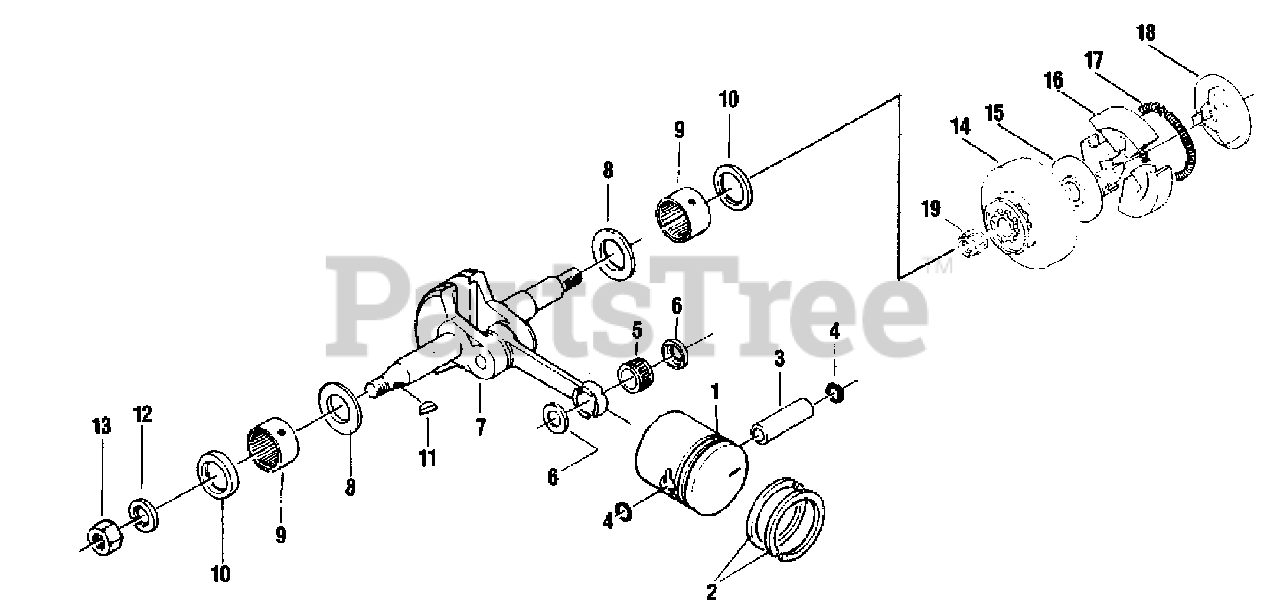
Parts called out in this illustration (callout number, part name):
1	PISTON
2	RING, PISTON
3	PIN, PISTON
4	RING, RETAINING
5	BEARING, NEEDLE
6	WASHER, THRUST
7	CRANKSHAFT ASSY
8	WASHER, THRUST
9	BEARING, NEEDLE
10	SEAL, OIL
11	KEY - 3X10
12	LOCKWASHER - 8
13	NUT
14	CLUTCH DRUM ASSY
15	HUB, CLUTCH
16	SHOE, CLUTCH
17	SPRING, CLUTCH
18	HUB, CLUTCH - OUTER
19	BEARING, NEEDLE
